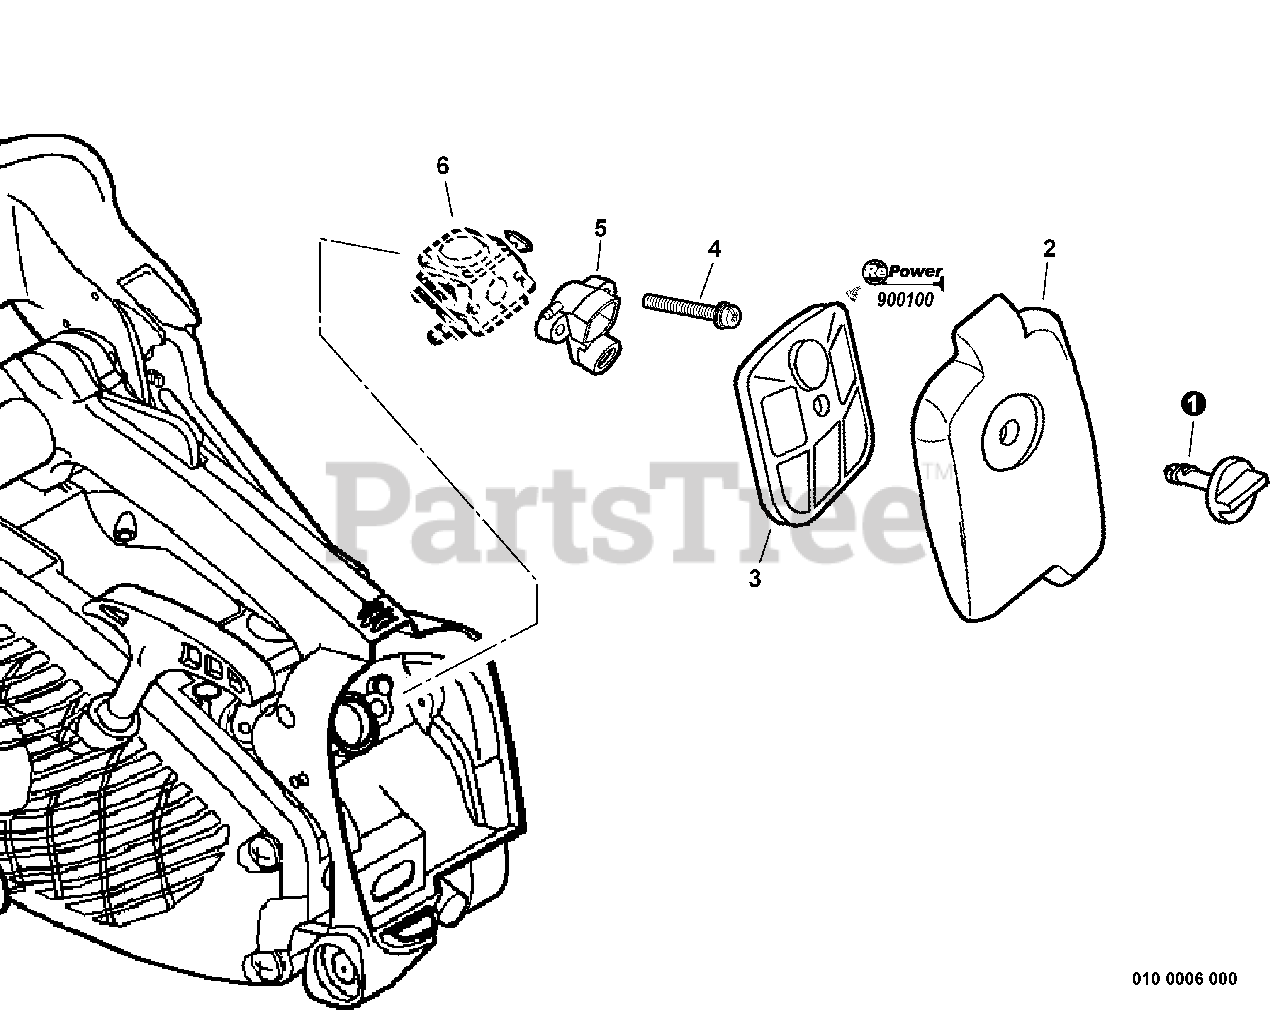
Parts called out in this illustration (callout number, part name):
1	THUMBSCREW
2	COVER, AIR FILTER
3	FILTER, AIR
4	SCREW 5×50
5	ADAPTOR, AIR FILTER
6	CARBURETOR
7	REPOWER TUNE-UP KIT
